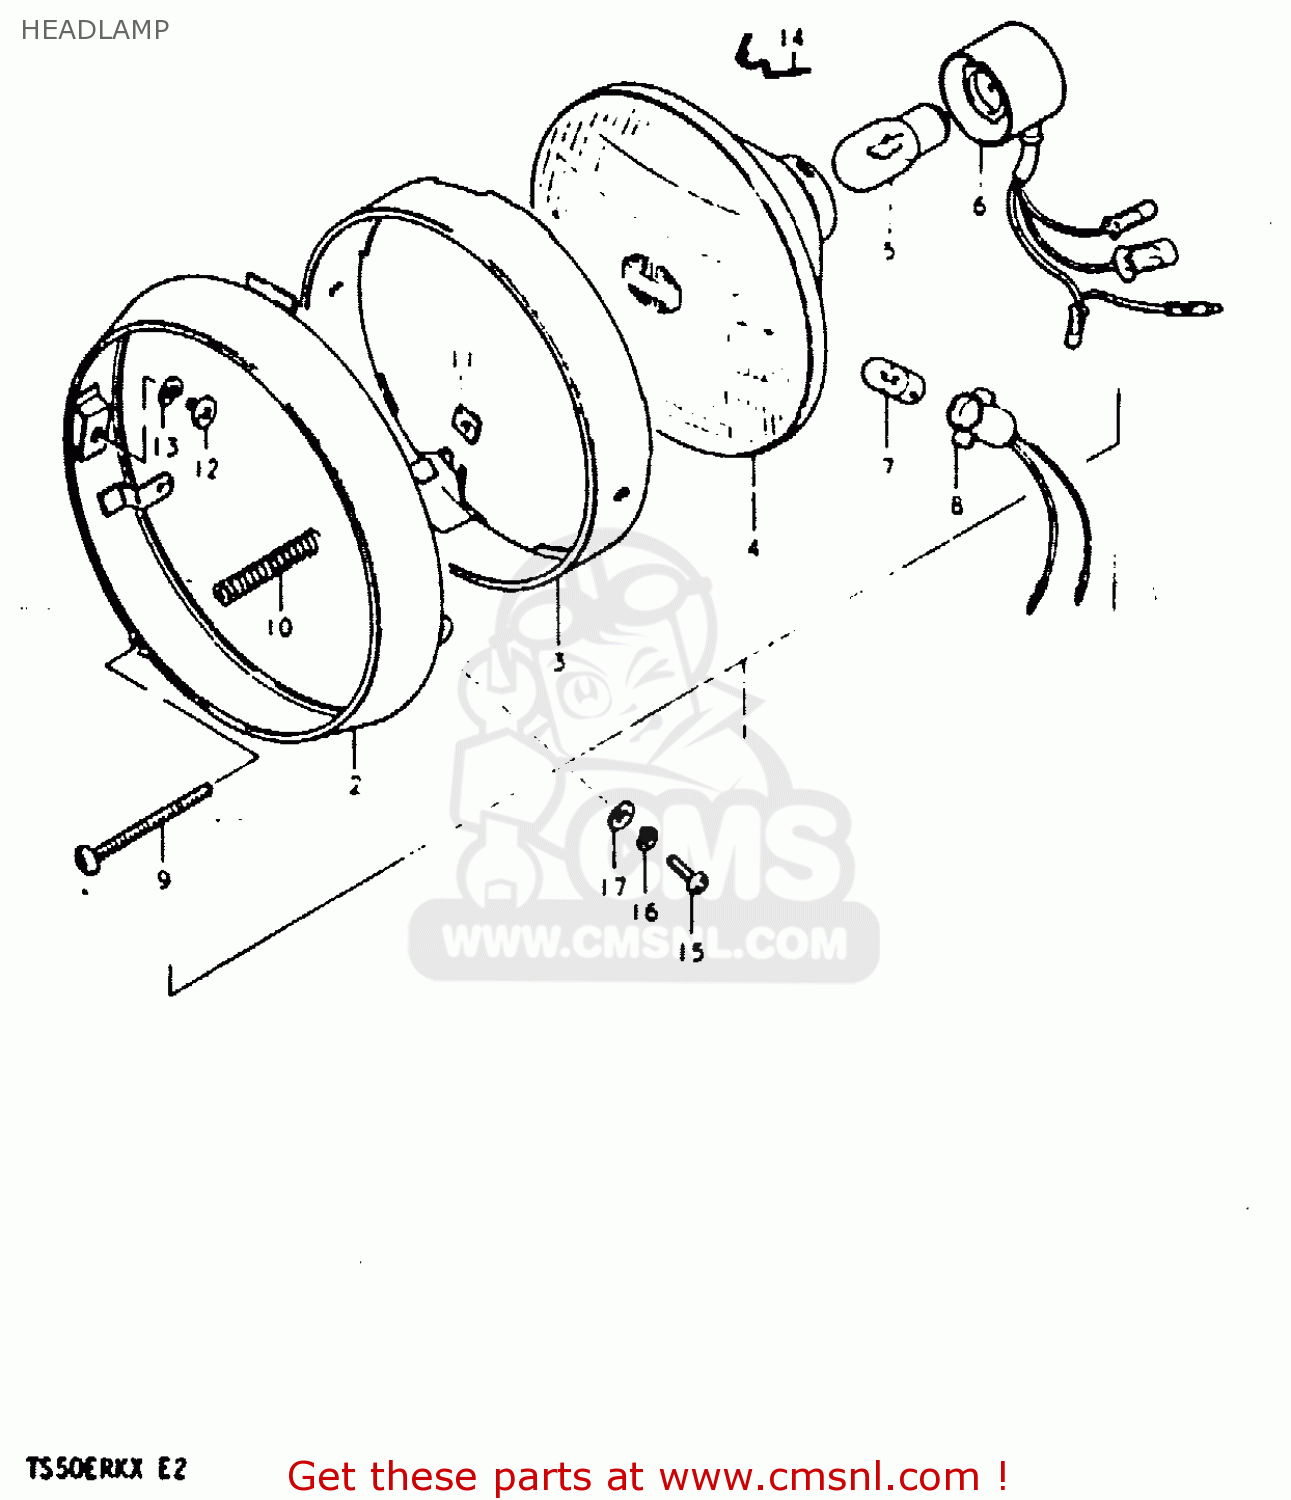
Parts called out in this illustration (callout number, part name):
1	HEADLAMP ASSY
2	RIM
3	RETAINER
4	UNIT
5	BULB (6V, 18/18W)
6	SOCKET
7	BULB(6V/3W)
8	SOCKET
9	SCREW,HEADLAMP ADJUST
10	SPRING,ADJUSTING
11	NUT
12	SCREW
13	LOCK WASHER
14	SPRING
15	SCREW
16	LOCK WASHER
17	WASHER
